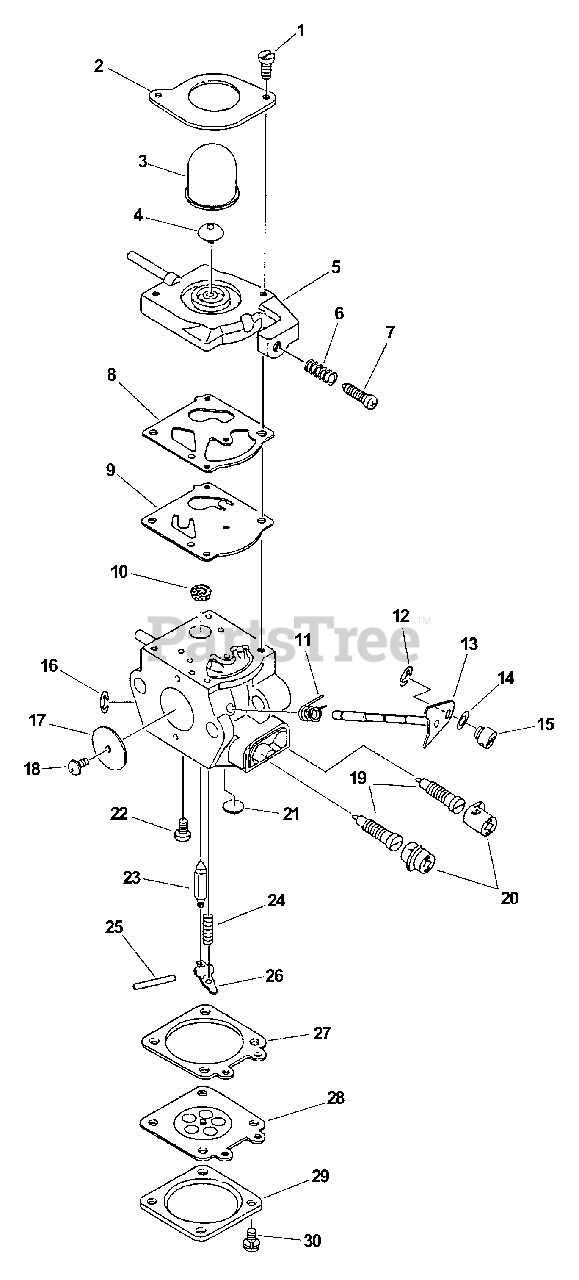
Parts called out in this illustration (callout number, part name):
1	SCREW, PUMP COVER
2	RETAINER, PURGE BULB
3	BULB, PURGE
4	VALVE, CHECK
5	BASE, PURGE
6	SPRING, IDLE ADJUST
7	SCREW, IDLE ADJUST
8	GASKET, PURGE
9	DIAPHRAGM, PURGE
10	STRAINER
11	SPRING, THROTTLE RETURN
12	RING, RETAINING
13	SHAFT, THROTTLE
16	RING, RETAINING
17	VALVE, THROTTLE
19	NEEDLE - MIXTURE
20	CAP, LIMITER
21	PLUG, WELCH
22	SCREW, METERING LEVER PIN
23	VALVE, INLET NEEDLE
24	SPRING, METERING LEVER
25	PIN, METERING LEVER
26	LEVER, METERING
27	GASKET, METERING
28	DIAPHRAGM, METERING
29	COVER, METERING
30	SCREW
